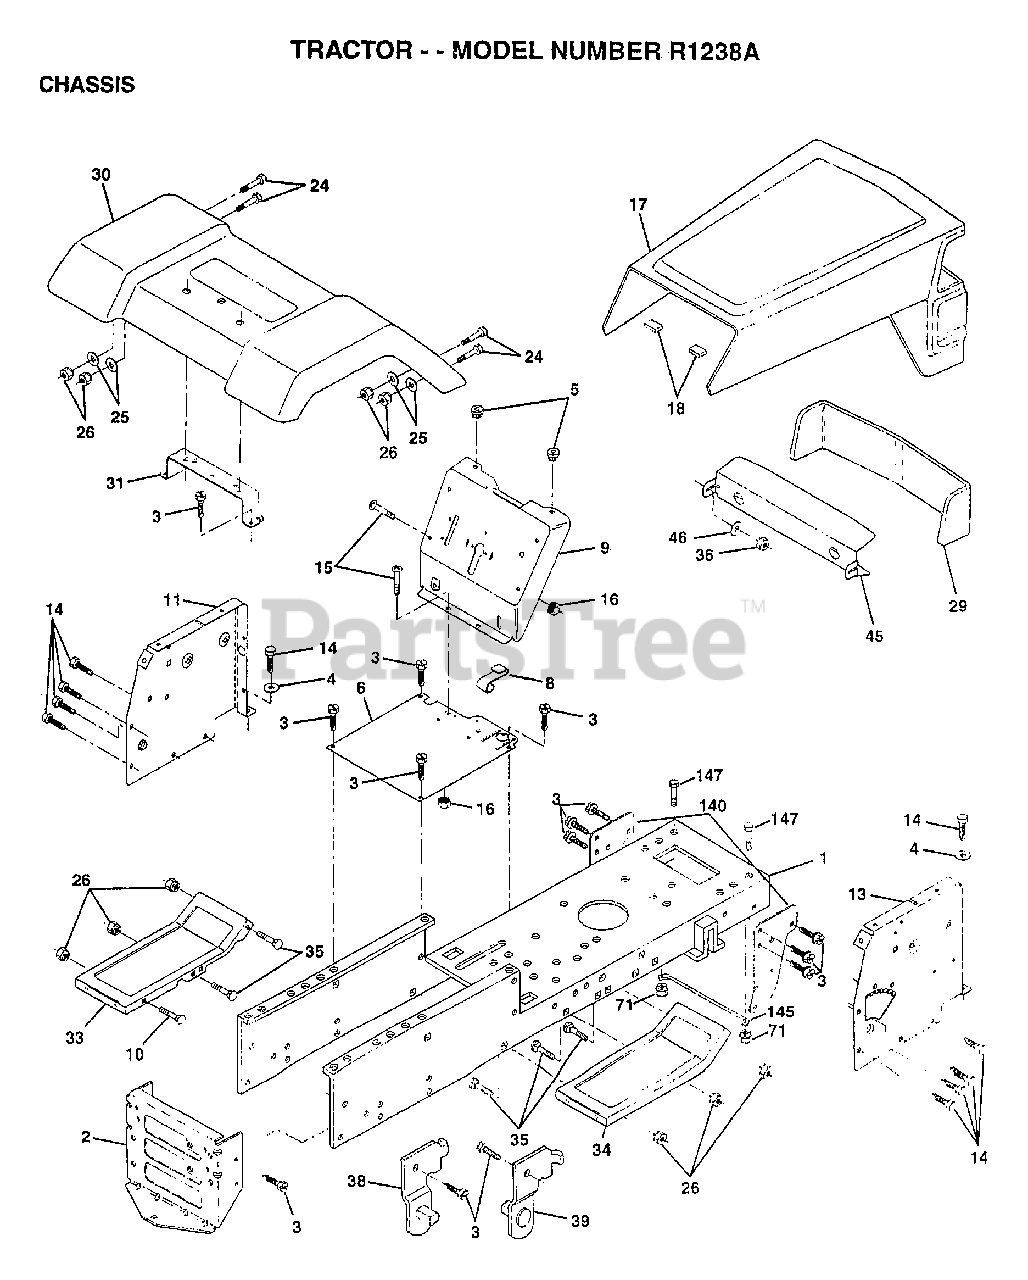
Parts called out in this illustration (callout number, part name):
1	CHASSIS ASM
3	SCREW
4	WASHER
5	BUMPER-HOOD/DASH
6	"SADDLE FLAT,SLKSC"
8	CLIP.RETAINER
9	DASH SILKSCR
11	"PANEL-DASH,LH"
14	SCREW LT
15	SCREW
17	HOOD/GRILL ASM
24	BOLT
25	WASHER
26	NUT
29	LENS SERVICE KIT
30	FENDER
31	BRKT FENDER
33	FOOTREST LH
34	FOOTREST RH
35	BOLT
36	PAL NUT LT
38	BRACKET ASM LH
39	BRACKET ASM RH
46	RETAINER
140	BRKT SUSPENSION
145	"ROD POVOT,CHASSIS"
147	BOLT LT
